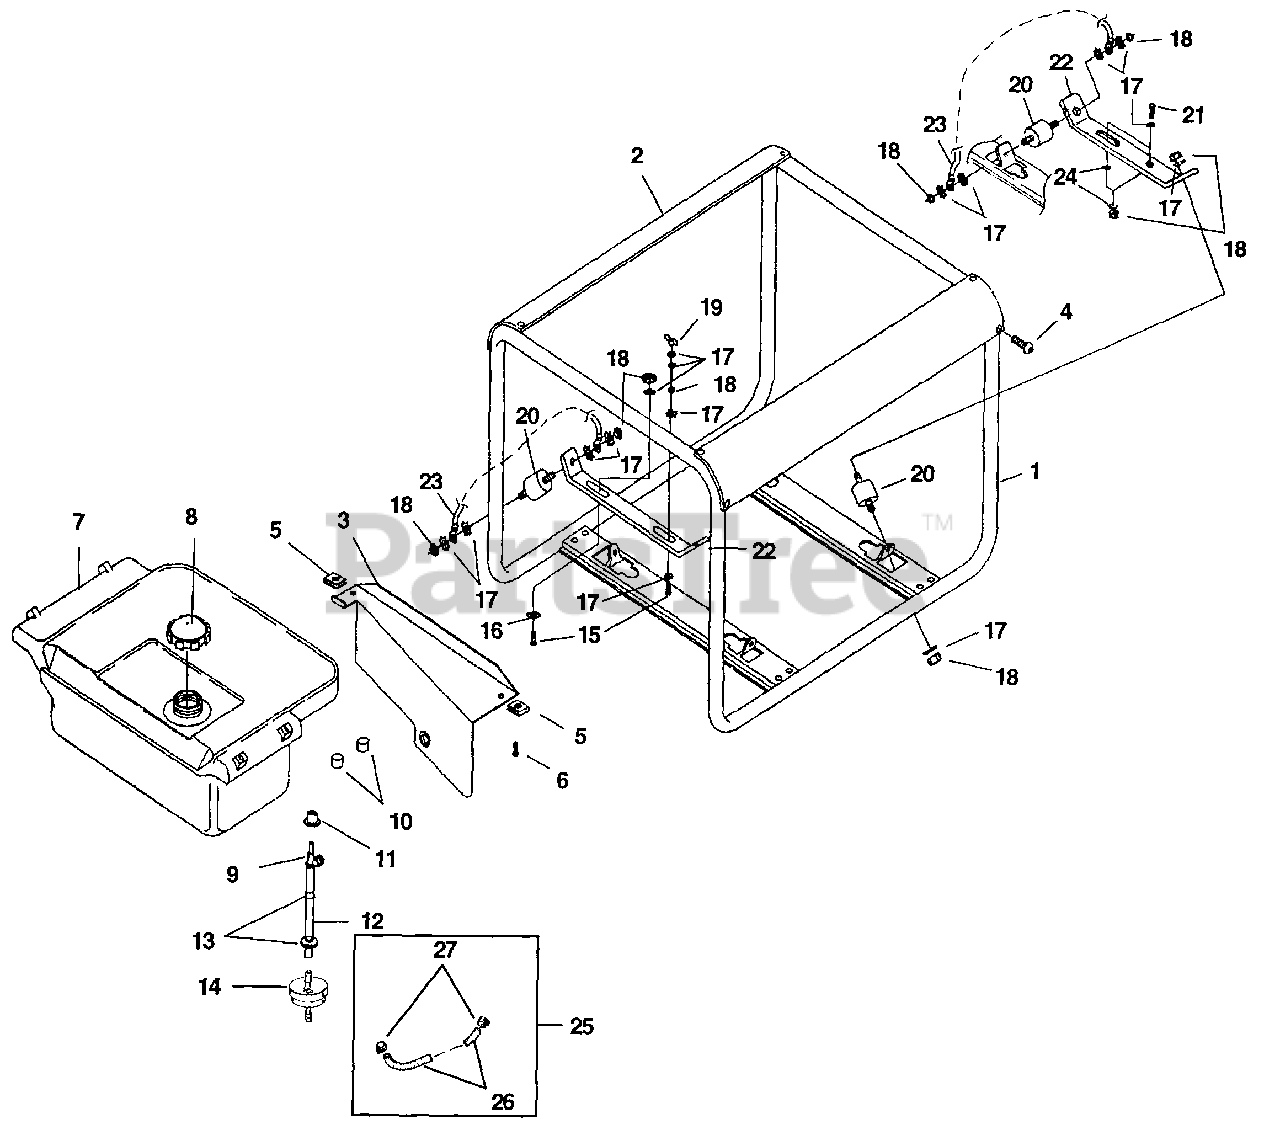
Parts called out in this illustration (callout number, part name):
1	Roll Cage
2	Brace - Tank Support
3	Shield - Fuel Tank
4	Screw - Torx (10-24 X 1/2")
5	Nut - Speed
6	Screw - Pan Hd. (8-32 X 3/8")
7	Fuel Tank (5 Gal.)
8	Cap - Fuel (2 1/4" Dia.)
9	Valve - Fuel
10	Pad - Fuel Tank
11	Bushing
12	Hose - Fuel (8")
13	Clip - Hose
14	Fuel Filter
15	Screw - Hex Hd. (5/16-18 X 1 1/4")
16	Washer - Flat
17	Washer - Lock (int.)
18	Nut - Hex (5/16-18)
19	Nut - Wing (5/16-18)
20	Isolator
21	Screw - Hex Hd. (5/16-18 X 3/4")
22	Support - Eng/Gen
23	Ground Strap
24	Washer, Lock -Int -Ext.
25	Fuel pipe
26	Rubber pipe
27	Hose clamp
